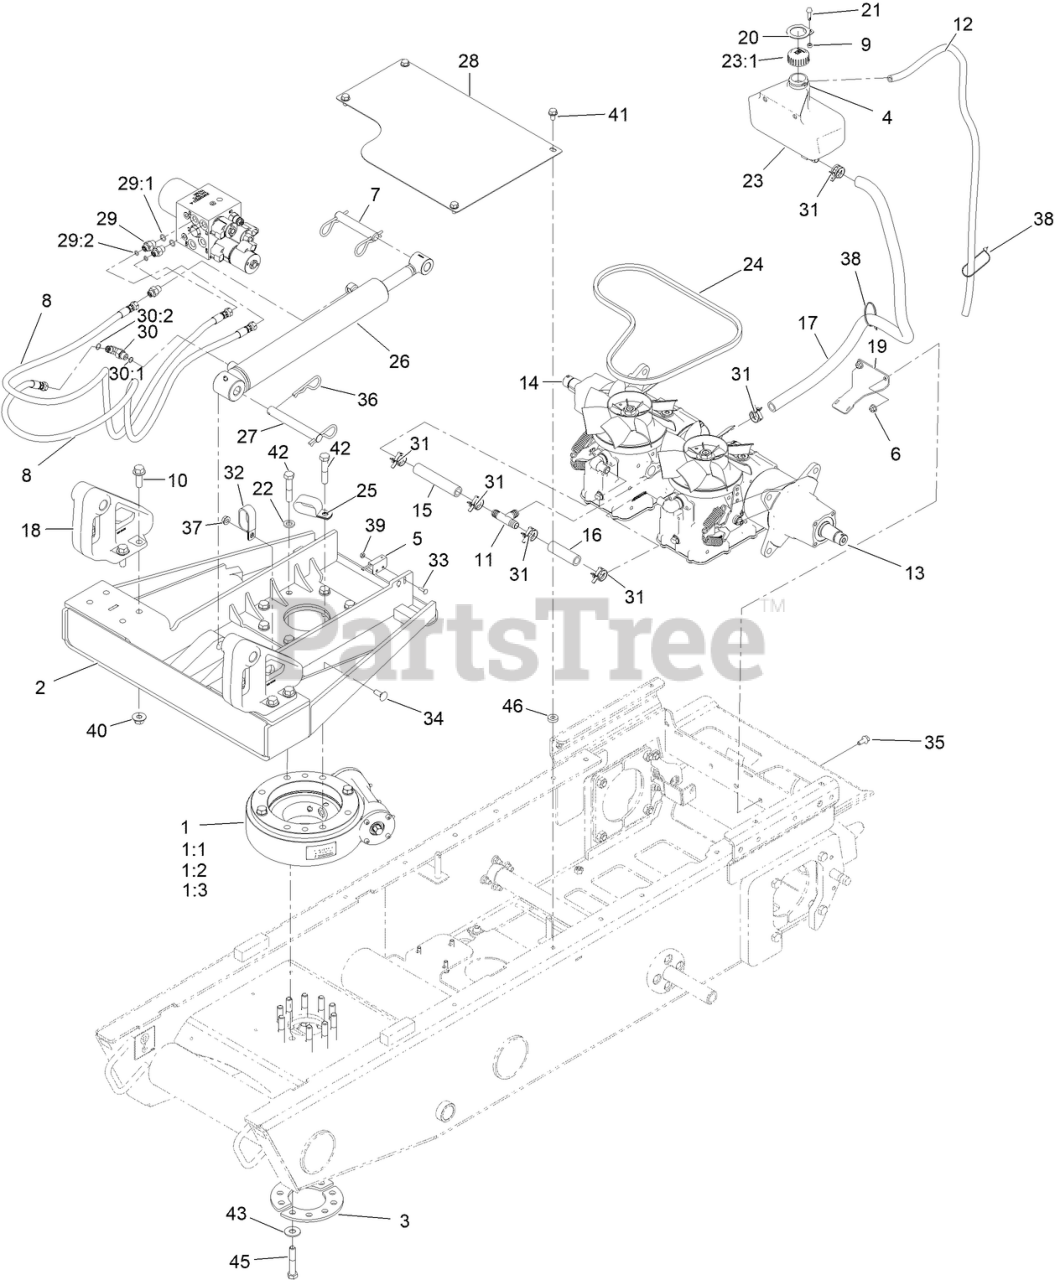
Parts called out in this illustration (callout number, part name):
1	DRIVE-SLEW
1:1	MOTOR-HYD, SLEW
1:2	SEAL-LIP
1:3	SEAL-TOP PLATE
2	TOP SWIVEL PLATE ASM [BLACK]
3	SPACER-SLEW MOUNT
4	CLAMP-HOSE
5	SWITCH-PROXIMITY
6	NUT-HF, NI
7	PIN-PIVOT
8	HOSE-HYD
9	SPACER
10	SCREW-HHF
12	HOSE-BREATHER, TRANSMISSION
13	LH HYDRO TRANSAXLE ASM
14	RH HYDRO TRANSAXLE ASM
15	HOSE-HYD, HYDRO
16	HOSE-HYD, HYDRO
17	HOSE-HYD, HYDRO
18	PIVOT-DUMP
19	BRACKET-HOSE RETAINER
20	LOCK-TANK
22	WASHER-THRUST
23	TANK-HYDRAULIC
23:1	CAP-VENTED
24	BELT-V
25	CLAMP-R, DOUBLE
26	CYLINDER, HYDRAULIC
27	PIN,PLAIN
28	SHIELD_COVER
29	FITTING-STRAIGHT
29:1	O-RING
29:2	O-RING
30	FITTING-ELBOW, 90 DEG
30:1	O-RING
30:2	O-RING
31	CLAMP-SC BAND
32	CLAMP-R, DOUBLE
33	SCREW-CARR
34	BOLT-CARR
35	SCREW-HHF
36	PIN-HAIR
37	NUT-HHF, WHIZ
38	TIE-CABLE
39	NUT-LOCK, NI
40	NUT-LOCK, FLANGE
41	SCREW-HHFTF
42	SCREW-HH
43	WASHER-FLAT
45	SCREW-HH
46	SPACER
